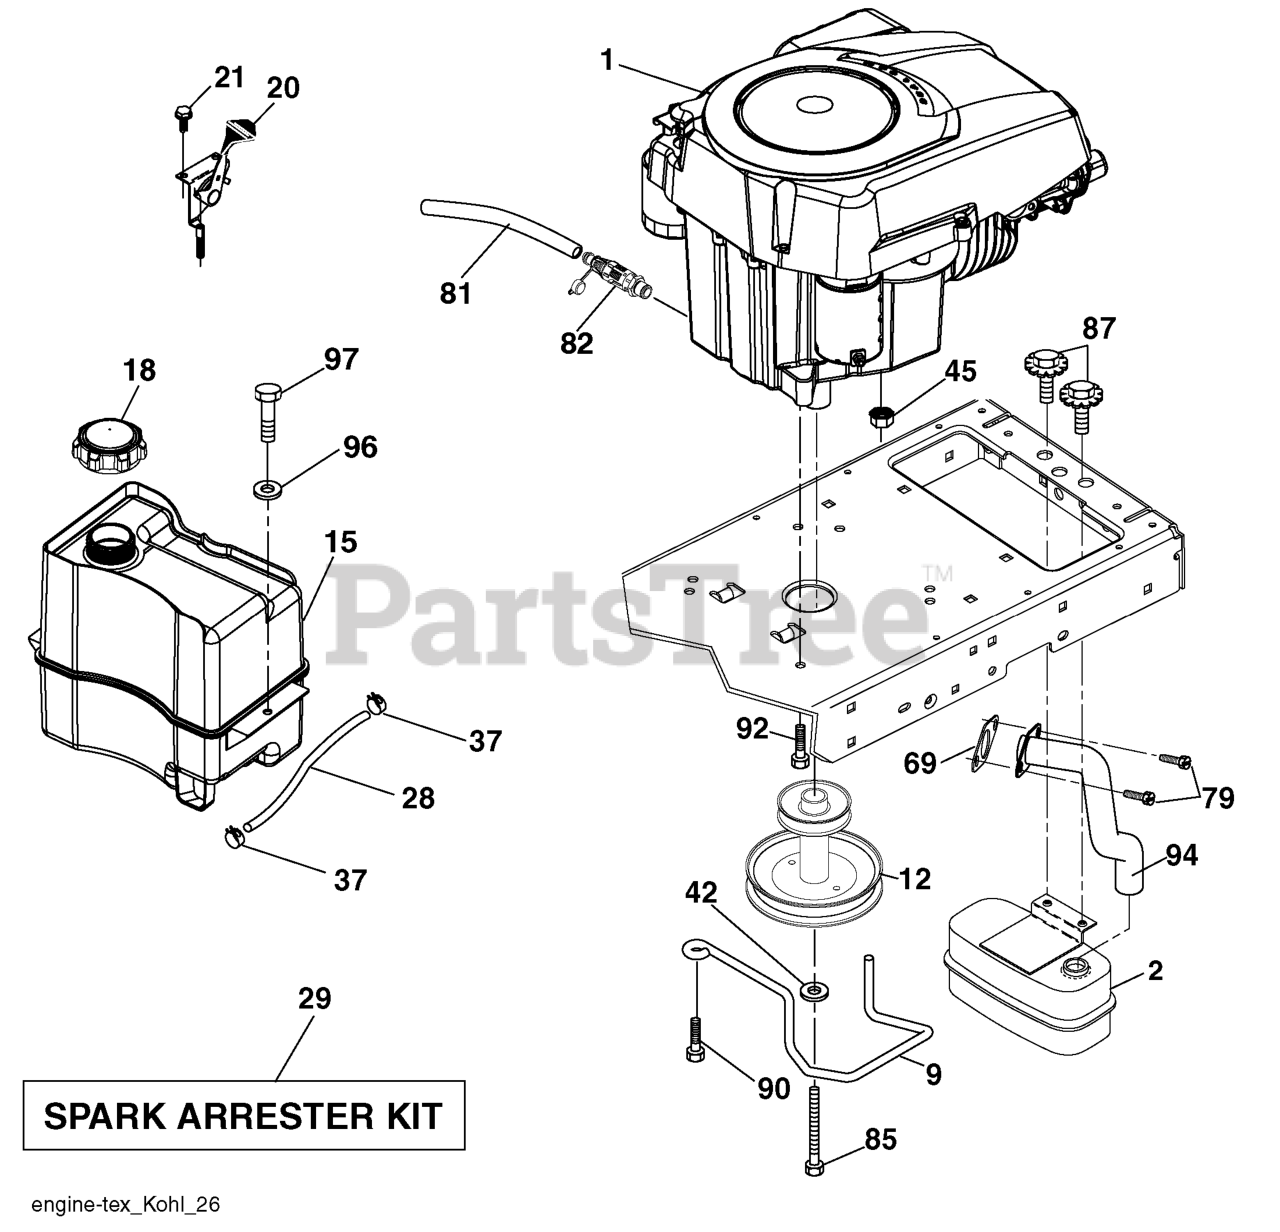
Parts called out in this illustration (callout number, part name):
2	MUFFLER.SINGLE.CYL.KOHL/B&S
9	KEEPER.BELT.ENGINE.4.2
12	RP_PULLEY ENGINE
15	TANK.ASM.FUEL.FR.2.5GA.
18	CAP ASM.FUEL.2.25"FR.
20	CONTROL.TH/CK.COBRA.KO
21	SCREW.#10 X 0.750.BOS
28	LINE.FUEL.20"FRONT.EMI
29	KIT.SPARK ARRESTOR 794945 B&S
37	HOSE CLAMP
42	LOCKWASHER
45	NUT
69	GASKET.EXHAUST.KOHLER
79	SCREW.SOCKET HD.5/16-1
81	TUBE, DRAIN OIL ASM.
82	VALUE.OIL.DRAIN
85	BOLT HEX 7/16-20X4-1/4"
87	BOLT.5/16-18UNCX3/4 W/SEMS.BLK
90	SCREW 3/8-16X1
92	SCREW 3/8-16X1
94	RP.TUBE.EXHAUST.KOHL.COURAGE
96	WASHER
97	SCREW HEXWSHR 1/4-20X3/4
